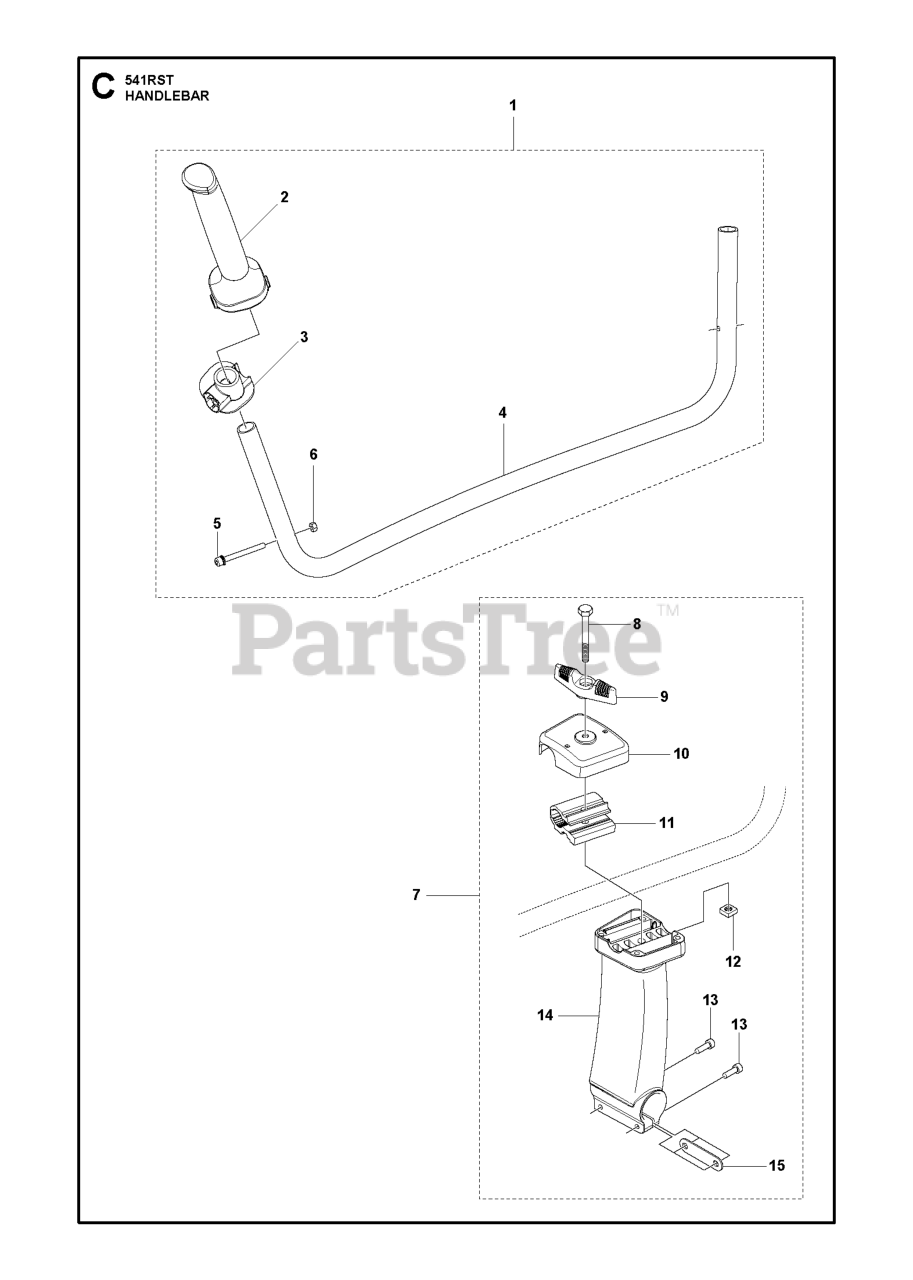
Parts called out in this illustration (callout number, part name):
8	SCREW EHHM
9	KNOB CLAMPING SLEEVE
10	PROTECTOR CLAMP
13	SCREW ITXSCM M5X20 T27 10.9 Z
